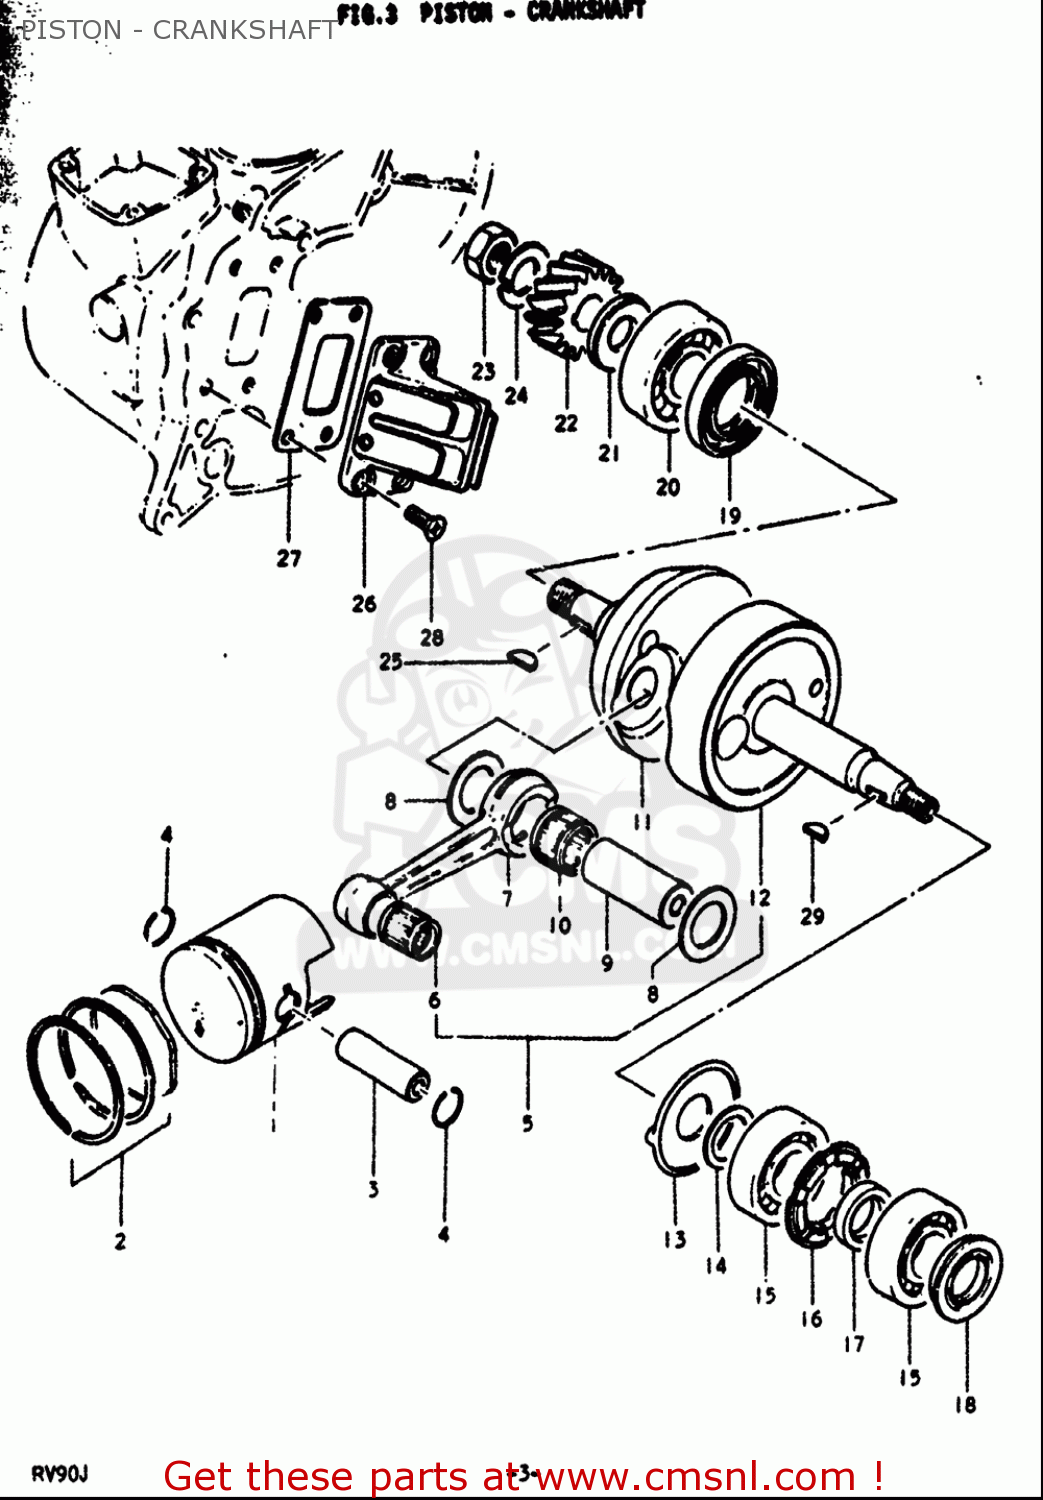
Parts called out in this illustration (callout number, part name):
1	PISTON
2	RING SET,PISTON
3	PIN,PISTON 14MM
4	RING,SNAP 14MM
5	CRANKSHAFT ASSY
6	BEARING(14X18X19.8)
7	ROD,CONNECTING
8	WASHER(19X32X1)
9	PIN,CRANK
10	BEARING(19X25X16)
12	CRANKSHAFT,LH
13	PLATE,CSHAFT OIL GUIDE
14	SHIM(20X28X0.5)
15	BEARING(20X47X14)
16	SPACER,CRANKSHAFT NO.1
17	SPACER(20X28X7)
18	SEAL,OIL(19.6X37X8)
19	SEAL,OIL(26X52X8)
20	BEARING(20X52X15)
23	NUT
25	KEY
27	GASKET,REED VALVE (NAS)
28	SCREW
29	KEY
